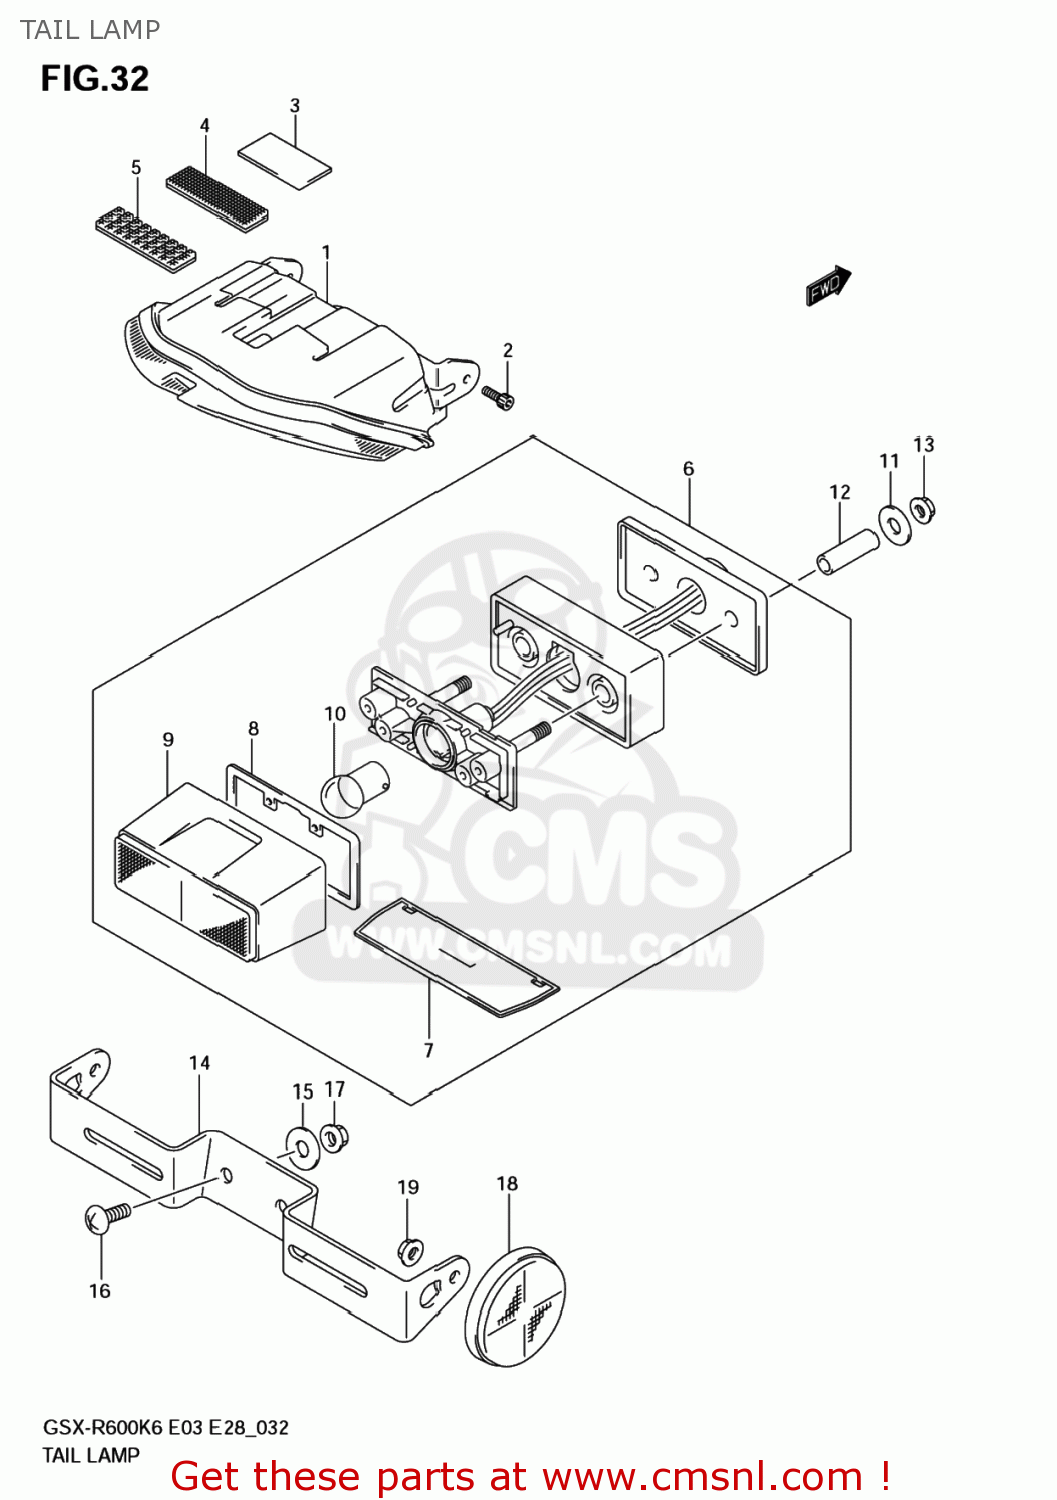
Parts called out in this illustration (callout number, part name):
1	LAMP ASSY,RR COMBINATION
2	BOLT
3	PROTECTOR,BATTERY(100X70X3)
4	FASTENER,RR COMB LAMP
5	FASTENER,RR COMB LAMP
6	LAMP ASSY,LICE
7	LENS LICENCE
8	GASKET (NAS)
9	COVER,LICENSE LAMP
10	BULB(12V5W,BF150-40160A)
11	WASHER(6.5X20X1.2)
12	SPACER(6.5X9X33.3)
13	NUT
14	BRACKET,LICENSE PLATE
15	WASHER(6.5X20X1.2)
16	SCREW
17	NUT
18	REFLECTOR ASSY,RR SIDE
19	NUT
